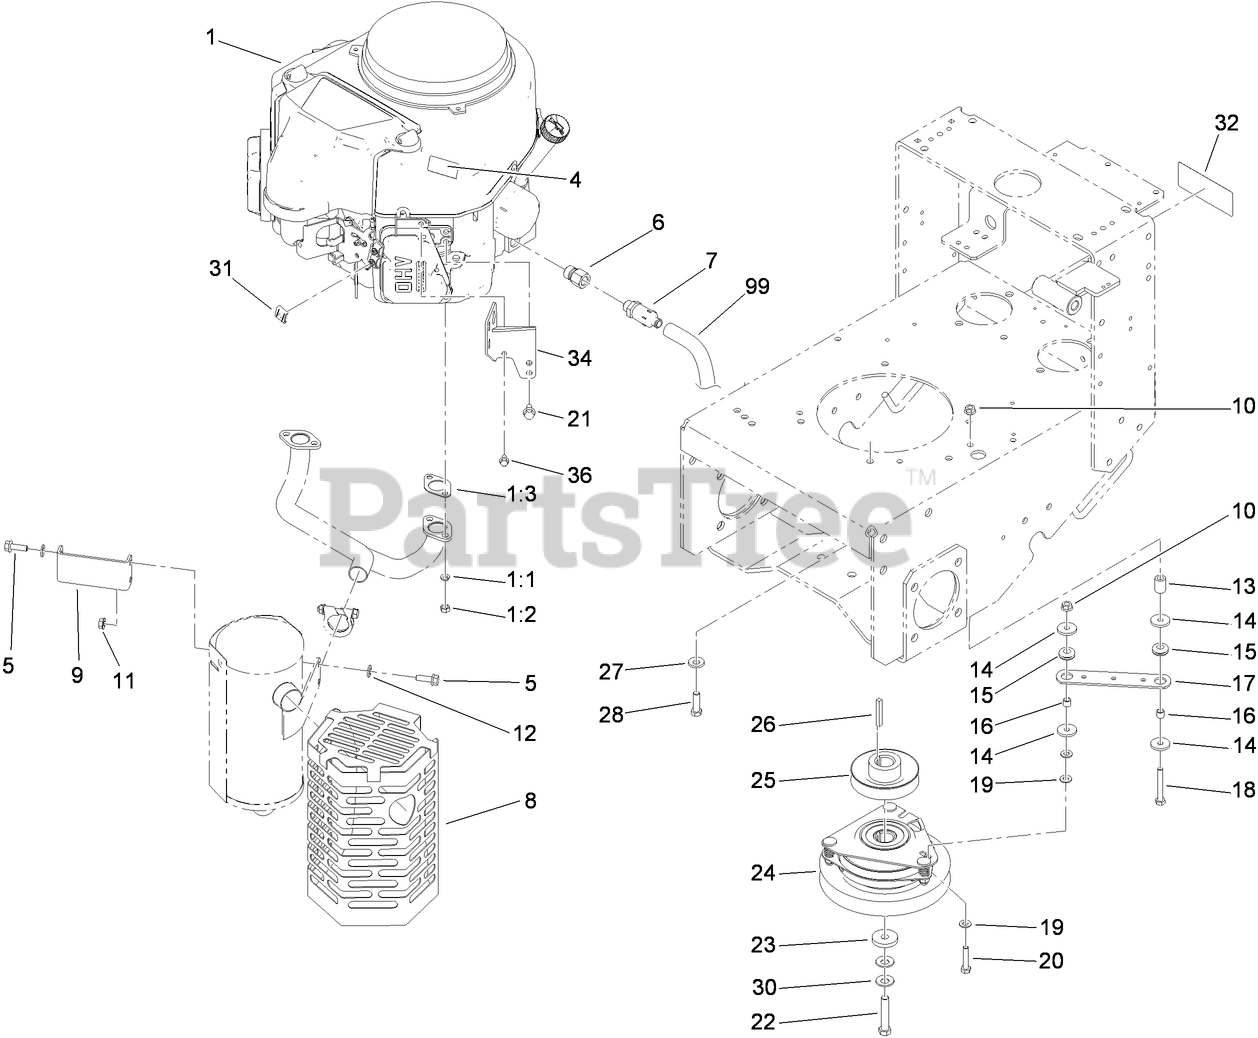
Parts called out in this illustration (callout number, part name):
1:1	WASHER-LOCK
1:3	GASKET-EXHAUST
4	DECAL-WARNING
5	SCREW-HHF
6	Adapter
7	VALVE-DRAIN, OIL
8	SHIELD-MUFFLER
9	BRACKET-SHIELD, MUFFLER
10	NUT-HF
11	NUT-HF, LOCK
12	WASHER-SPRING
13	TUBE-RETAINER
14	WASHER
15	GROMMET
16	SPACER
17	STRAP-CLUTCH, BRAKE
18	SCREW-HH
19	WASHER-PLAIN
20	SCREW-HH
21	SCREW-HHF
22	SCREW-HH
23	WASHER
24	CLUTCH / BRAKE ASM
25	Pulley
26	KEY-SQUARE
27	WASHER-BELLEVILLE
28	SCREW-HH
30	WASHER-SPRING
31	CLAMP-CABLE
32	DECAL-CAUTION
34	BRACKET-MUFFLER
36	SCREW-HHF
99	HOSE-DRAIN, OIL
